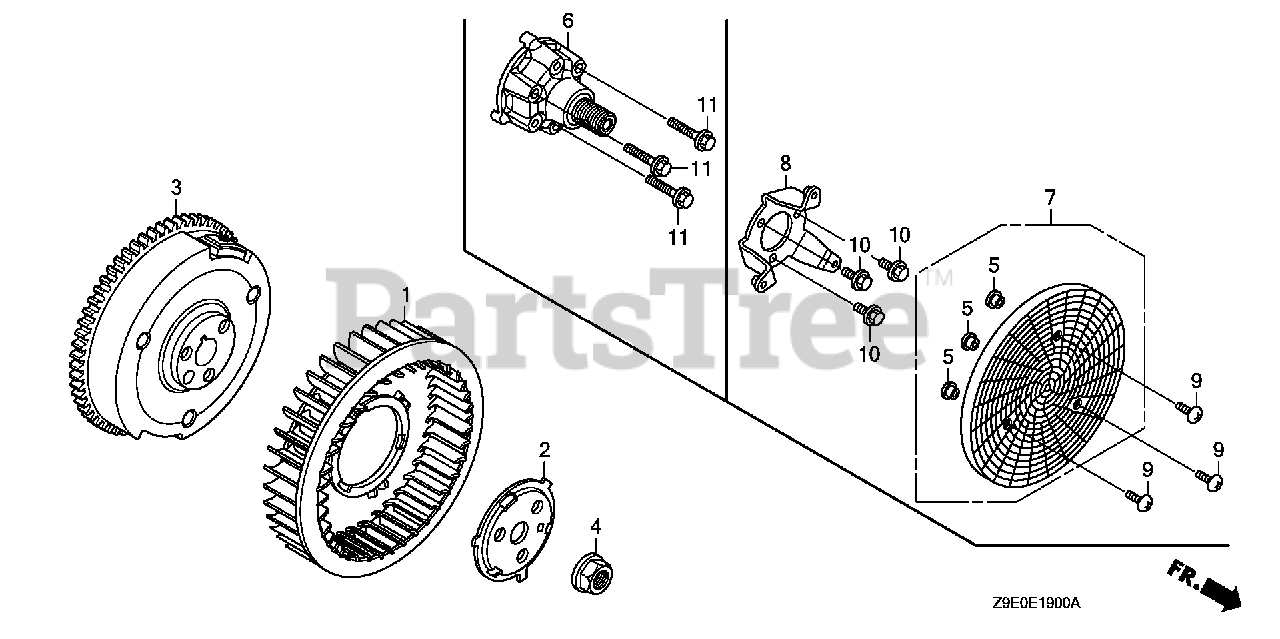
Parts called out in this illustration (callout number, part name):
1	FAN, COOLING
2	PLATE, COOLING FAN SETTING
4	NUT, SPECIAL (20MM)
